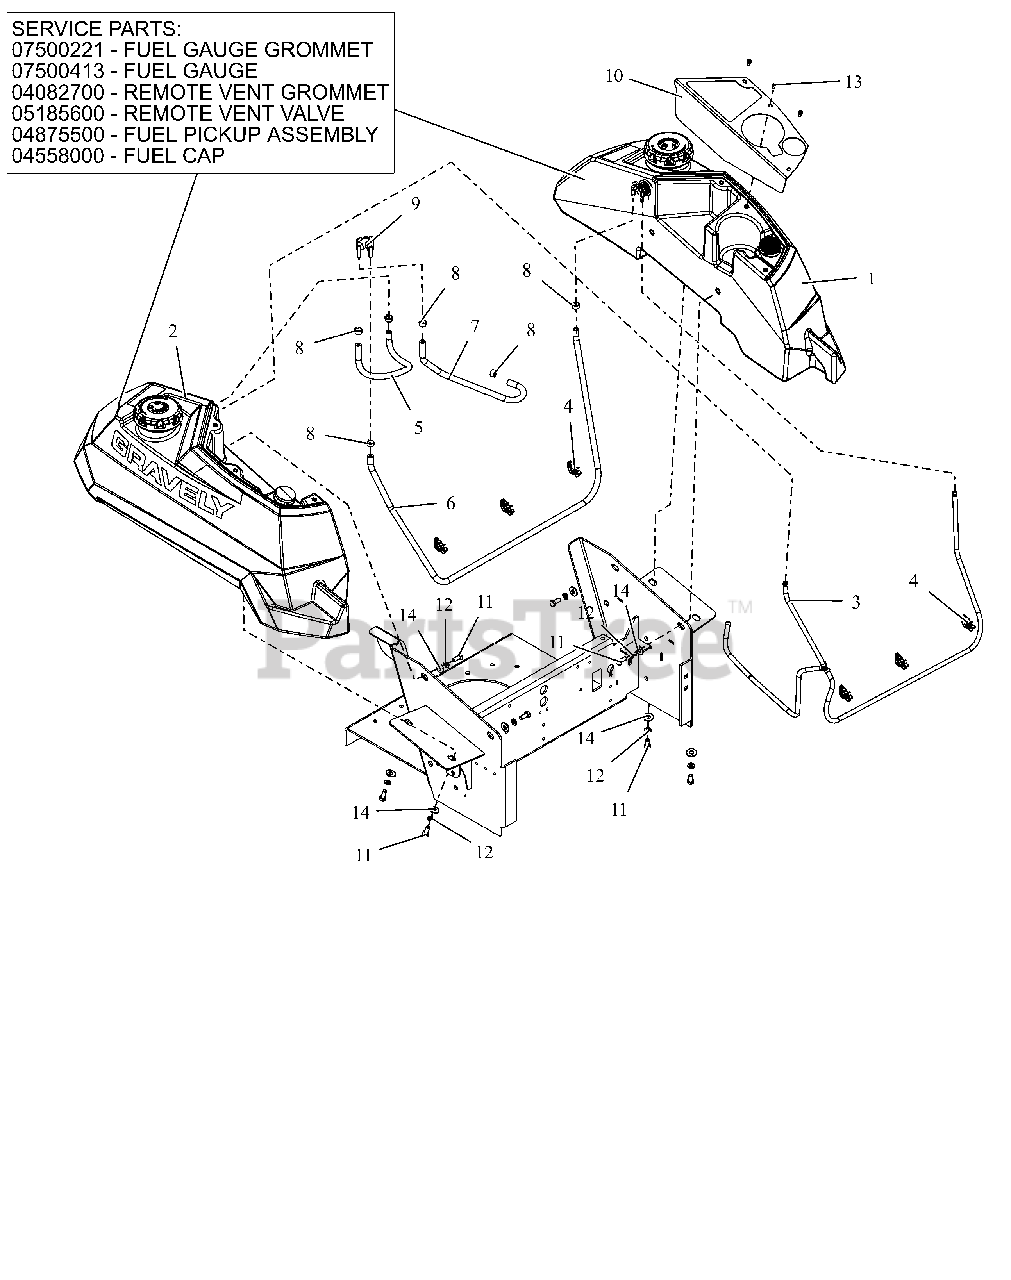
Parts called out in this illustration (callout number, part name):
1	ASM, LH - PT100 FUEL TANK
2	ASM, RH - PT100 FUEL TANK
2	GROMMET, FUEL GAUGE
2	GAUGE, REMOTE SEALED FUEL
2	GROMMET, REMOTE VENT NITRILE
2	VALVE, COMBINATION VENT 3/16
2	ASSM,LRG TANK FUEL PICKUP LINE
2	CAP, FUEL VENTIN AUTOLOCK
3	ASM, VAPOR LINE
4	WIRE CLIP
5	HOSE, .25 LOW-PERM BULK GAS
6	HOSE, .25 LOW-PERM BULK GAS
7	HOSE, .25 LOW-PERM BULK GAS
8	CLAMP, FUEL LINE
9	VALVE, FUEL
10	PT100 CUPHOLDER PANEL - RED
11	@BLT-HEX .31-18X.75 GR5 YWZC
12	@WSHR-LK .31X.078 REG YWZC
13	SCR-MCH 10-24X.38 HWHSTAINLESS
14	@WSHR-FL-STL.38X.875X.083 YWZC
